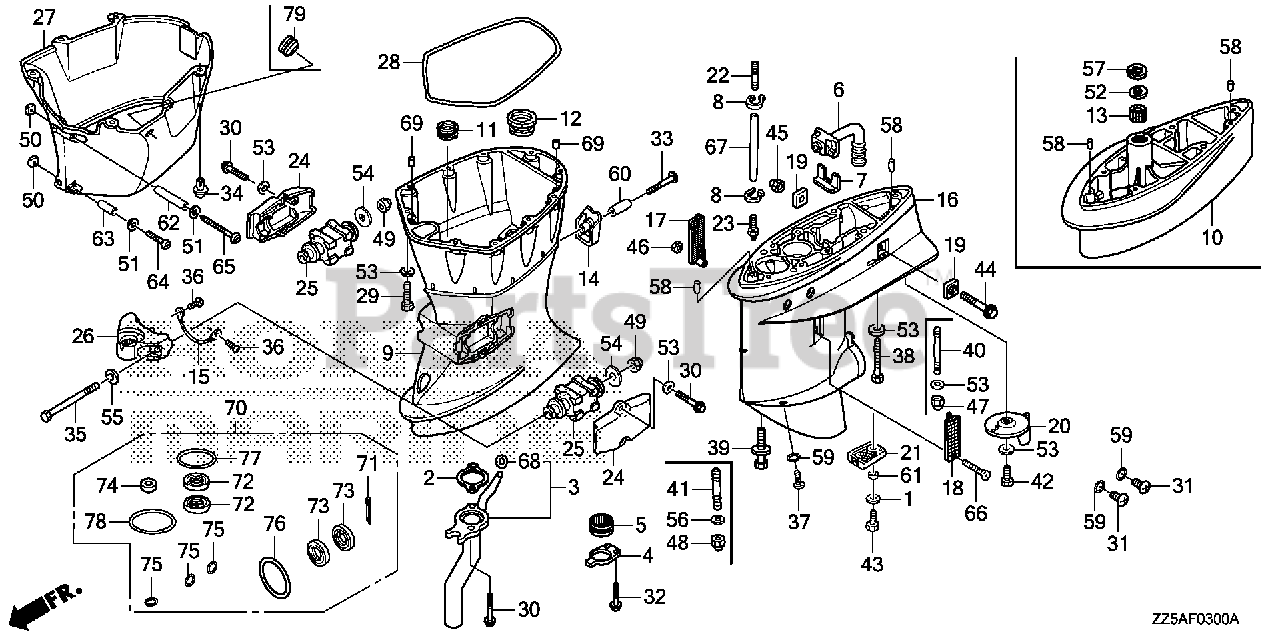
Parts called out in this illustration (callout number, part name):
1	WASHER, PIVOT
2	GASKET, EX. PIPE
3	PIPE KIT, EX.
4	HOLDER, EX. PIPE GROMMET
5	GROMMET, EX. PIPE
6	TUBE, WATER (LOWER)
7	PLATE, RUBBER SETTING
8	BAND, WIRE
9	CASE, EXTENSION *NHB14M* (AQUA MARINE SILVER METALLIC)
10	SEPARATOR, EXTENSION *NHB14M* (AQUA MARINE SILVER METALLIC)
11	GROMMET, EXTENSION CASE
12	RUBBER, DRAIN PLUG
13	BUSH, VERTICAL SHAFT
14	COVER, DRAIN PLUG *NHB14M* (AQUA MARINE SILVER METALLIC)
15	WIRE, LEAD (1.5X116MM)
16	CASE, GEAR *NHB14M* (AQUA MARINE SILVER METALLIC)
17	SCREEN, R. WATER
18	SCREEN, L. WATER
19	METAL, ANODE
20	TAB, TRIM *NHB14M* (AQUA MARINE SILVER METALLIC)
21	SCREEN, WATER (LOWER)
22	END, NIPPLE
23	NIPPLE, SENSOR
24	HOUSING, R. MOUNTING (LOWER) *NHB14M* (AQUA MARINE SILVER METALLIC)
25	RUBBER, MOUNT (LOWER)
26	HOUSING, CENTER MOUNTING (LOWER) *NHB14M* (AQUA MARINE SILVER METALLIC)
27	COVER (LOWER) *NHB14M* (AQUA MARINE SILVER METALLIC)
28	RUBBER, COVER (LOWER)
29	BOLT, HEX. (8X35)
30	BOLT, FLANGE (8X25)
31	BOLT, OIL CHECK
32	BOLT, FLANGE (6X20)
33	SCREW, SPECIAL (6X35)
34	SCREW, RIVET (8X15)
35	BOLT, HEX. (12X162)
36	SCREW, PAN (6X8)
37	BOLT, DRAIN PLUG
40	BOLT, STUD (8X164)
41	BOLT, STUD (10X132)
42	BOLT, HEX. (8X20)
43	BOLT, HEX. (6X16)
44	BOLT, FLANGE (6X25)
45	NUT, SELF-LOCK (6MM)
46	NUT, SELF-LOCK (5MM)
47	NUT, SELF-LOCK (8MM)
48	NUT, SELF-LOCK (10MM)
49	NUT, SELF-LOCK (12MM)
50	NUT, PLATE (5MM)
51	WASHER, PLAIN (5MM)
52	WASHER (20MM)
53	WASHER, PLAIN (8MM)
54	WASHER, PLAIN (12MM)
55	WASHER, PLAIN (12MM)
56	WASHER, PLAIN (10MM)
57	CIRCLIP (INNER) (30MM)
58	PIN, DOWEL (6X10)
59	O-RING (6.9X1.45)
60	COLLAR, DISTANCE (6X10.5X25)
61	COLLAR, WATER SCREEN (LOWER)
62	COLLAR, DISTANCE (5X7X38)
63	COLLAR, DISTANCE (5X7X23)
64	SCREW, PAN (5X30)
65	SCREW, PAN (5X45)
66	SCREW, OVAL (5X40)
67	BULK HOSE, VACUUM (5X3000) (5X300)
68	GROMMET, EX. BREATHER PIPE
69	PIN, DOWEL (6X15)
70	CASE KIT, GEAR
71	PIN, SPLIT (4.0)
72	SEAL, WATER (17X30X7)
73	SEAL, WATER (22X35X7)
74	SEAL, WATER (7MM)
75	O-RING (6.9X1.45)
76	O-RING (69X3.1)
77	O-RING (41.7X3.5)
78	O-RING (47X3.1)
79	GROMMET, TUBE
